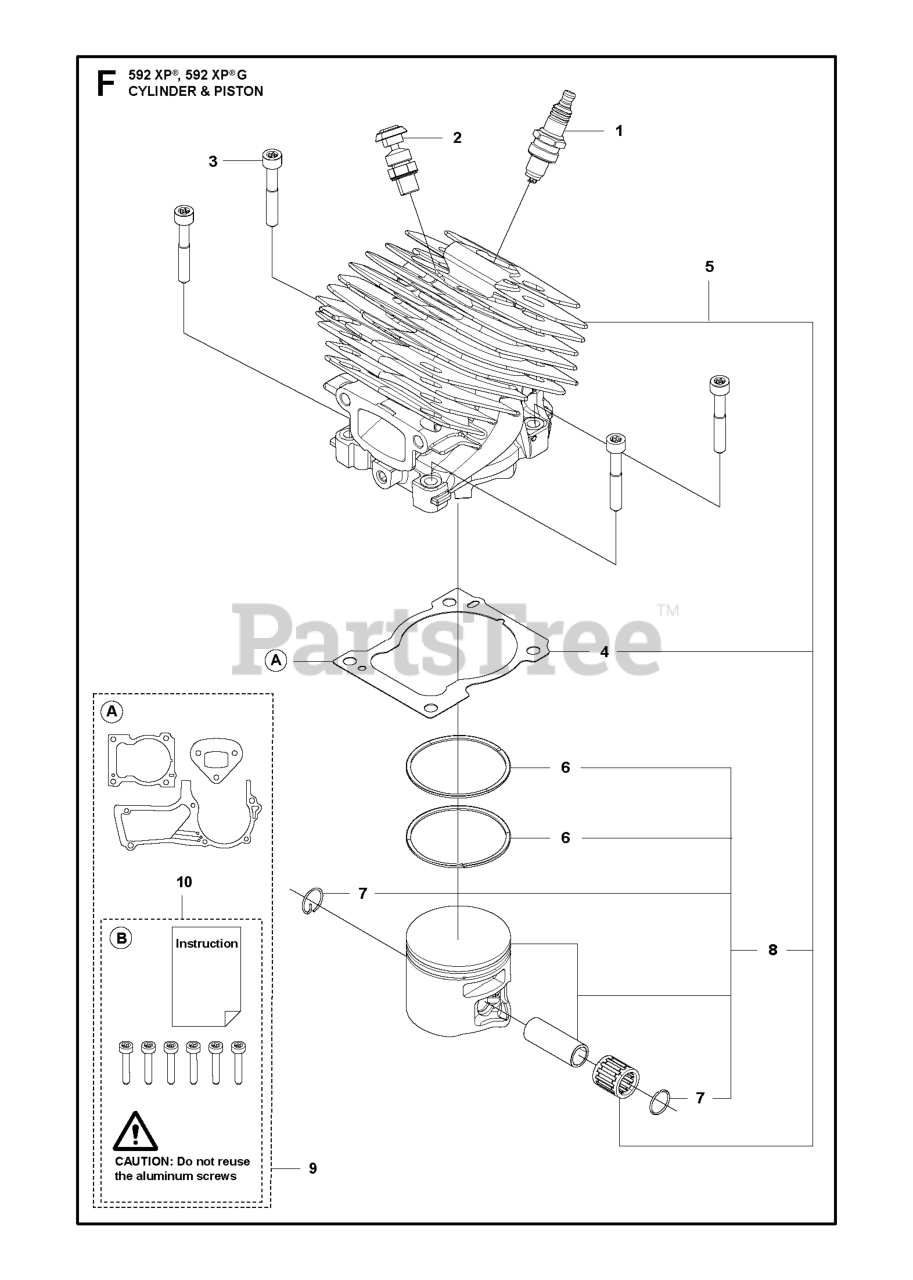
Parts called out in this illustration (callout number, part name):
1	CMR6H SPARK PLUG NGK
2	DECOMPRESSION VALVE
3	SCREW ISO 14579 M 6 X 40 12.9
4	GASKET CYLINDER 0
5	CYLINDER KIT D55 H592 SPARE PA
6	PISTON RING HK-55X1.2
8	PISTON ASSY D55 SPARE PART
9	GASKET KIT SPARE PART H592
10	SCREW KIT ALUMINUM 6 PCS
